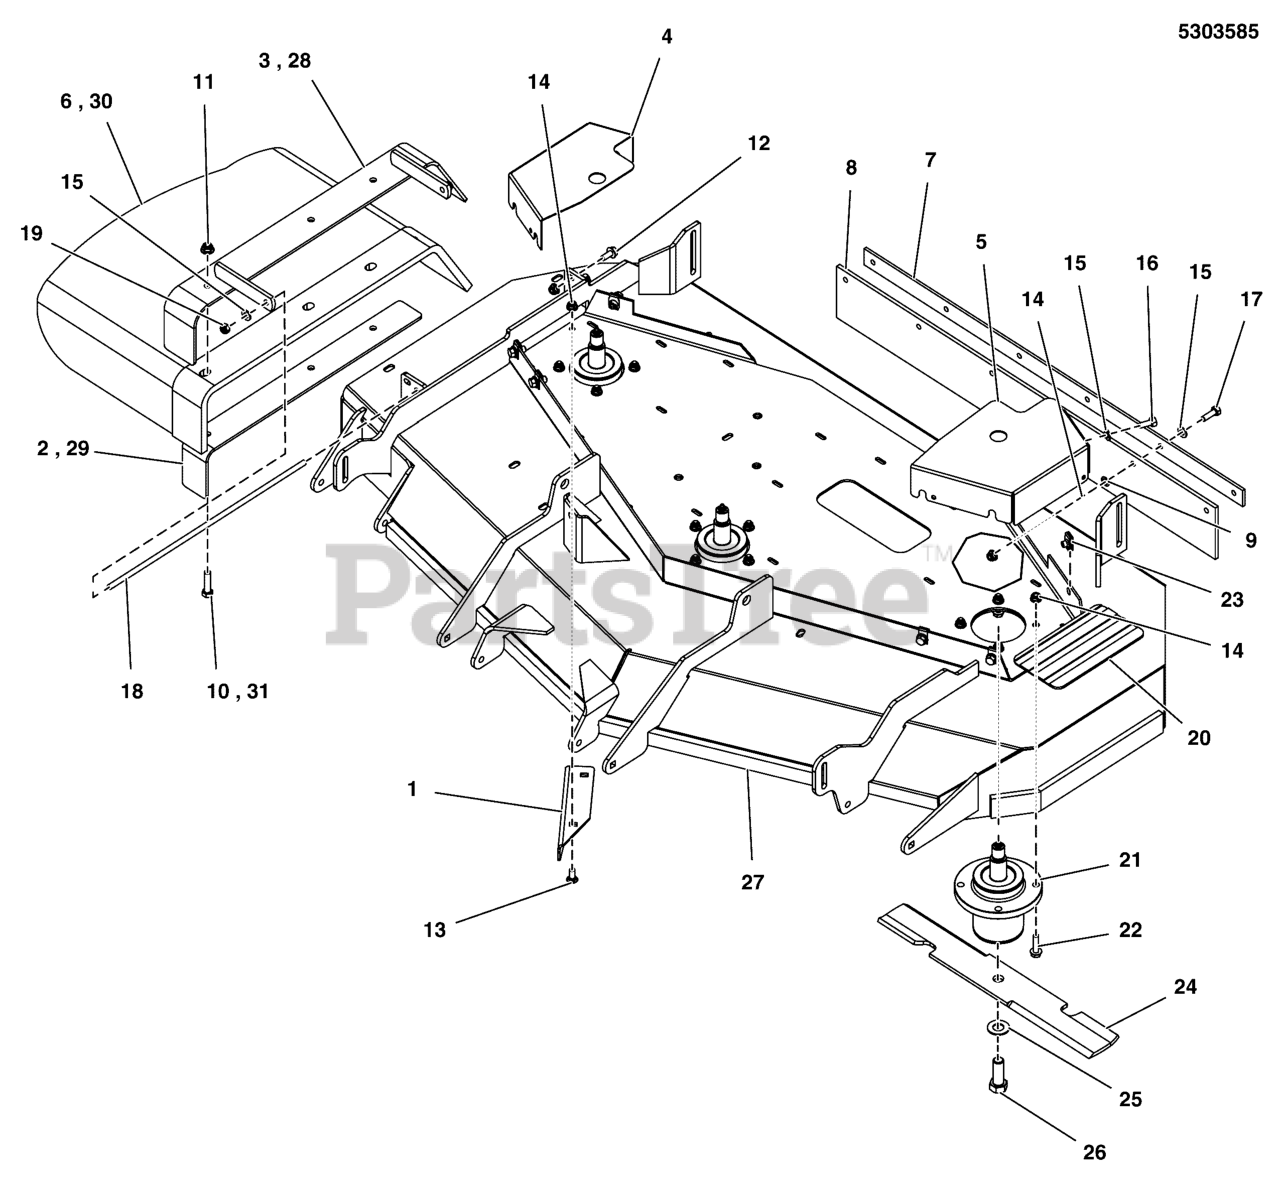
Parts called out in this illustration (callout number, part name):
1	PLATE, DEFLECTOR, 52 DECK - BLK
2	SUPPORT, DISCHARGE CHUTE, 52 - BLK
3	WELD, FRAME, CHUTE, 52 - BLK
4	GUARD, 52 DECK, IS2000, RH - RED
5	GUARD, 52" DECK, IS2000 - LH - RED
6	CHUTE, Discharge
7	PLATE, SUPPORT - BLK
8	FLAP, STRIPER, 52 DECK
9	5/16 PUSH-ON NUT RETAINER, STL, CZ
10	BOLT, 3/8-16 X 1-1/2" GD5 CZ
11	NUT, 3/8-16 HEX NYLOCK FLANGE
12	BOLT, 5/16-18 X 3/4 GD5
13	BOLT, 5/16-18 X 3/4, CARRIAGE
14	NUT, 5/16-18 HEX NYLOCK FLANGE
15	WASHER, 5/16" SAE
16	BOLT, 5/16-18 X 3/4 GD5
17	BOLT, 5/16-18 X 1 GD5 YZ
18	ROD, MOUNT, CHUTE 61, CZ
19	NUT, 5/16-24 HEX NYLON LOCK
20	SAFETY WALK, 4.00 X 7.50
21	ASSM, SPINDLE, LOW PROFILE
22	BOLT, 5/16-18 X 1 1/4 FLANGE
23	BODY CLIP, 5/16-18-7GA MATERIAL
24	BLADE SET, SET OF THREE (SV)
25	WASHER, BLADE BOLT, 9/16" F436, CZ
26	BOLT, 5/8-11 X 1-3/4 GD8
27	DECK SHELL W/ DECALS, 52, IS2100Z (SV)
27	DECK SHELL W/ DECALS, 52, IS2100Z ANSI-EXP (SV)
28	WELD, MOUNT, DISCHARGE CHUTE - BLK
29	SUPPORT, DISCHARGE CHUTE - BLK
30	CHUTE, RUBBER DISCHARGE (5104442)
31	BOLT, 3/8-16 X 1-1/2, CARRIAGE, GD5, CZ
